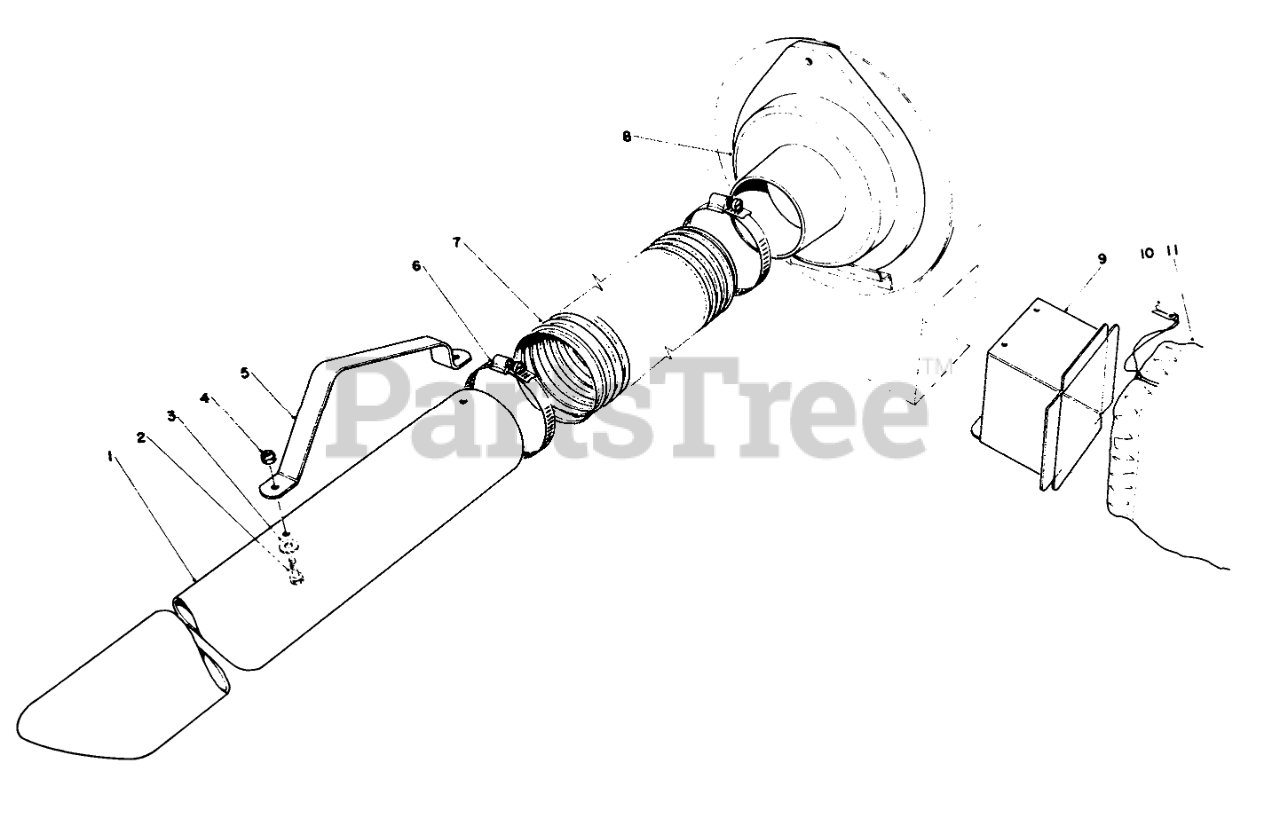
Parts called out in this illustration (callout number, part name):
1	NOZZLE
2	SCREW-HH
3	SPECIAL WASHER
4	NUT-KEPS
5	NOZZLE HANDLE
6	Clamp
7	VACUUM HOSE
8	ADAPTOR HOSE TO HSG
9	HOUSING WA BLOWER BAG
10	BAG CORD FASTENER
11	GIANT BAG(29-9860) WW
